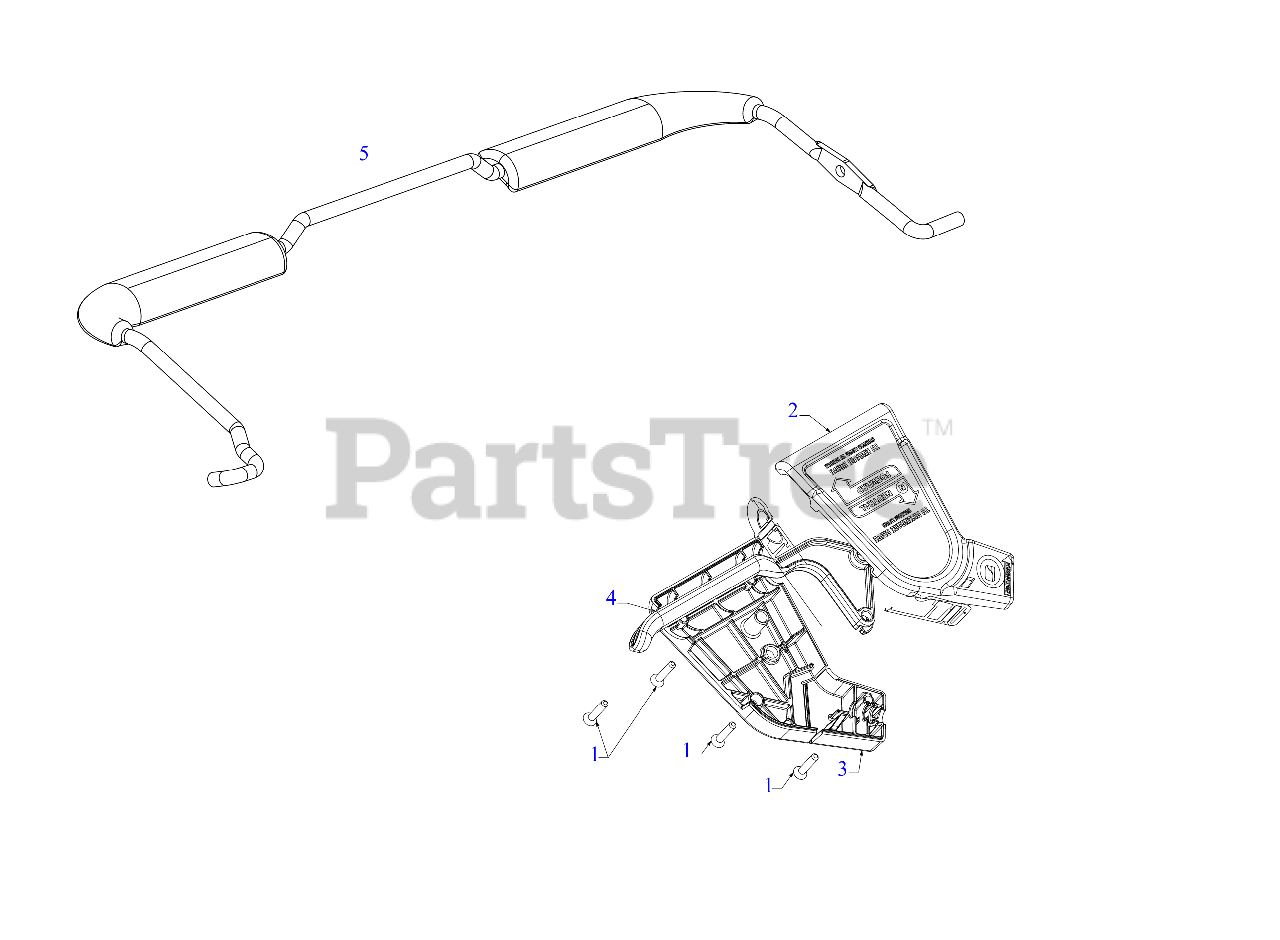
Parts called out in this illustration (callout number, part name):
1	SCREW #10-16 x 1.00
2	KIT-DRIVE CONTROL
3	SQUEEZEBOX CONTROL COVER
4	SPEED ENGAGEMENT LEVER (SBD GRAY)
5	OPERATOR BAIL (LIBERTY RED)
